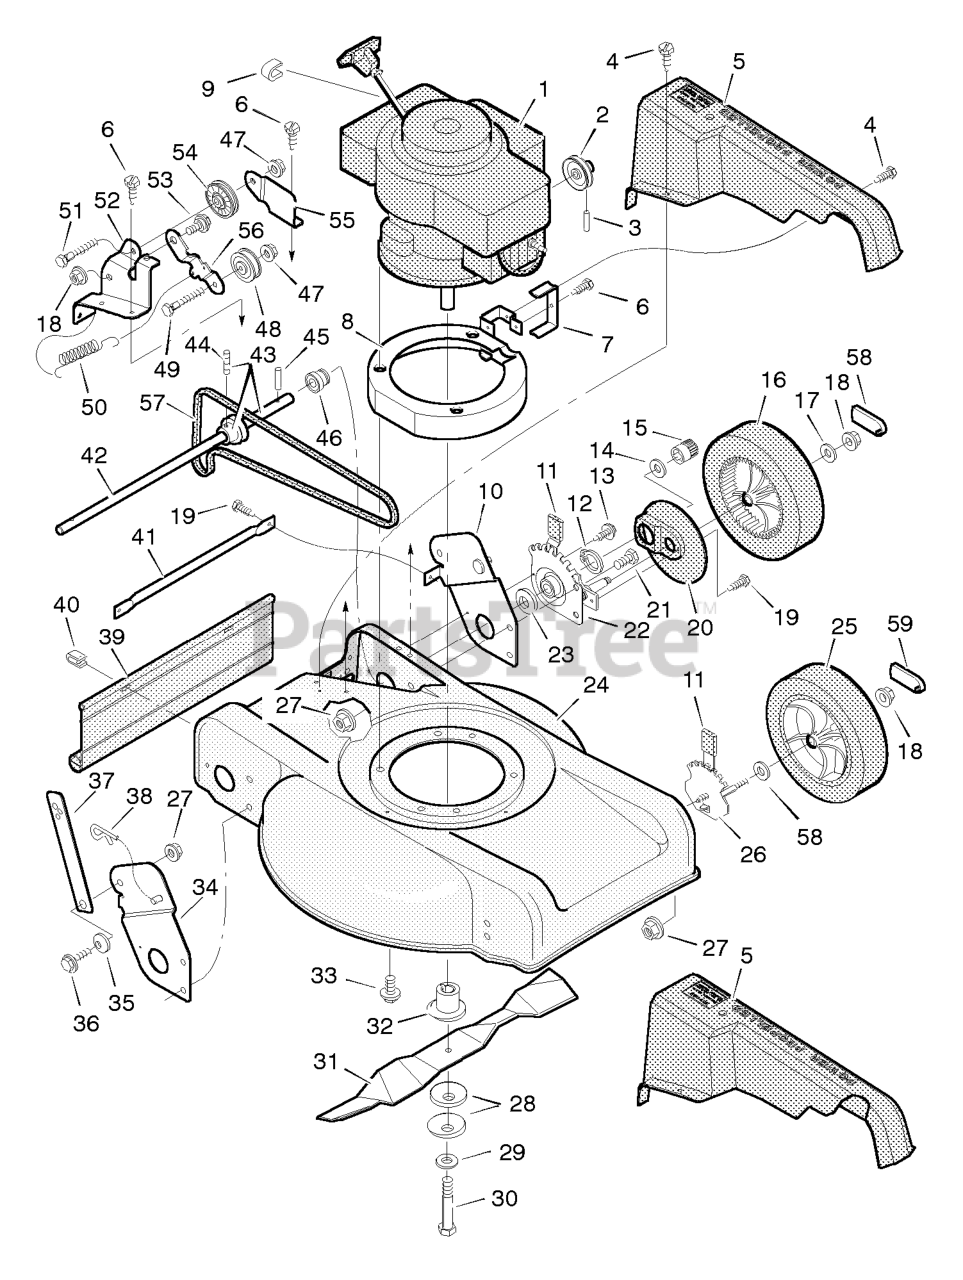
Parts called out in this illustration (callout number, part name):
1	Engine *
2	Pulley, Engine
3	Pin, Spring
5	Belt Guard
7	Guide, Belt
8	Plate, Spacer
9	Stop, Rope
10	Handle Bracket, Left
12	Ring, Retaining
15	Gear, Right Pinion
16	Wheel, Drive
17	Washer
18	Nut
20	Cover, Dust
21	Bolt, Hex
22	Height Adjuster, Right Rear
24	Housing
25	WHEEL & TIRE ASSEMBLY, White, 8"
26	Height Adjuster, Front
27	Nut, Hex
28	Washer, Belleville
30	Bolt, Blade
32	Adapter, Blade
33	Bolt, Engine
34	Handle Bracket, Right
36	Bolt, Shoulder
37	Support, Handle
38	Pin, Hair
39	Guard, Rear
40	Retainer
41	Brace, Rear
43	Axle, Pulley & Set Screw
44	Setscrew
45	Pin, Drive
46	Bearing Retainer
47	Locknut, Flange
48	Pulley, Idler
52	Bracket, Idler
53	Bolt, Shoulder
54	Pulley, Idler
55	Support, Idler
56	Arm, Idler
59	Hub Cap (Standard)
